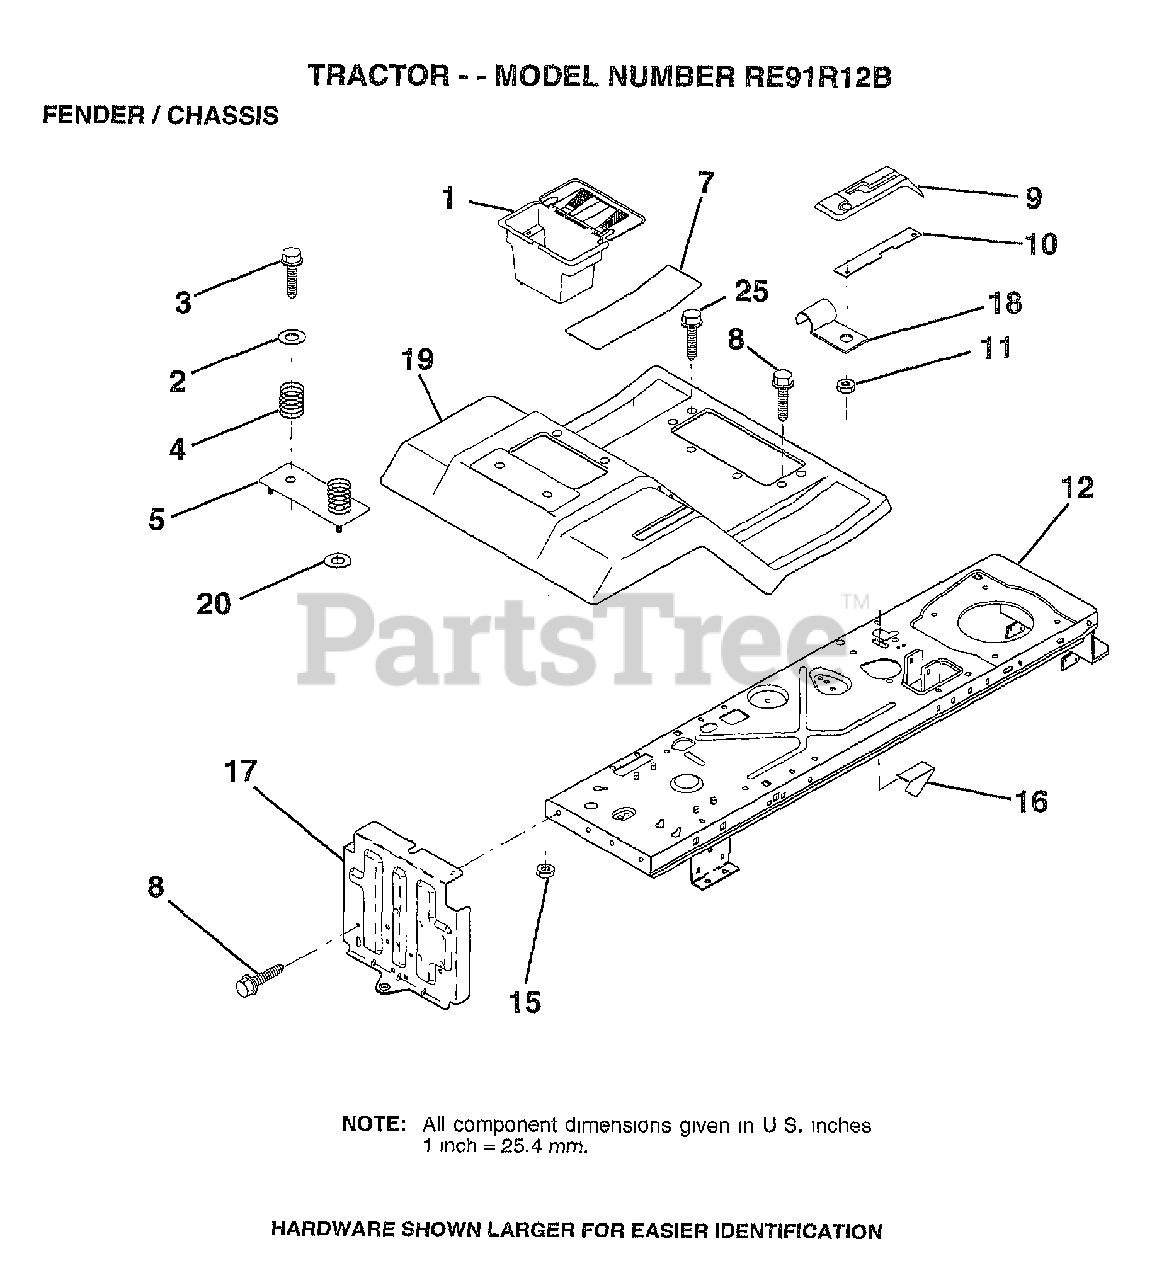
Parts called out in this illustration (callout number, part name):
1	"CASE,BATTERY.MECH"
2	WASHER
3	SCREW
4	SPRING COMPRESSIO
5	BTRY FENDER PLATE
7	PAD FOOTREST
8	SCREW
9	CONSOLE SHIFT
10	PLATE LOCK SHIFT
11	NUT
12	CHASSIS.WELD.ASM.
15	NUT HXKEP 1/4X20
17	DRAWBAR ASM LR
18	"CLIP,INSULATOR"
19	FENDER/FOOT MS505
25	SCREW
